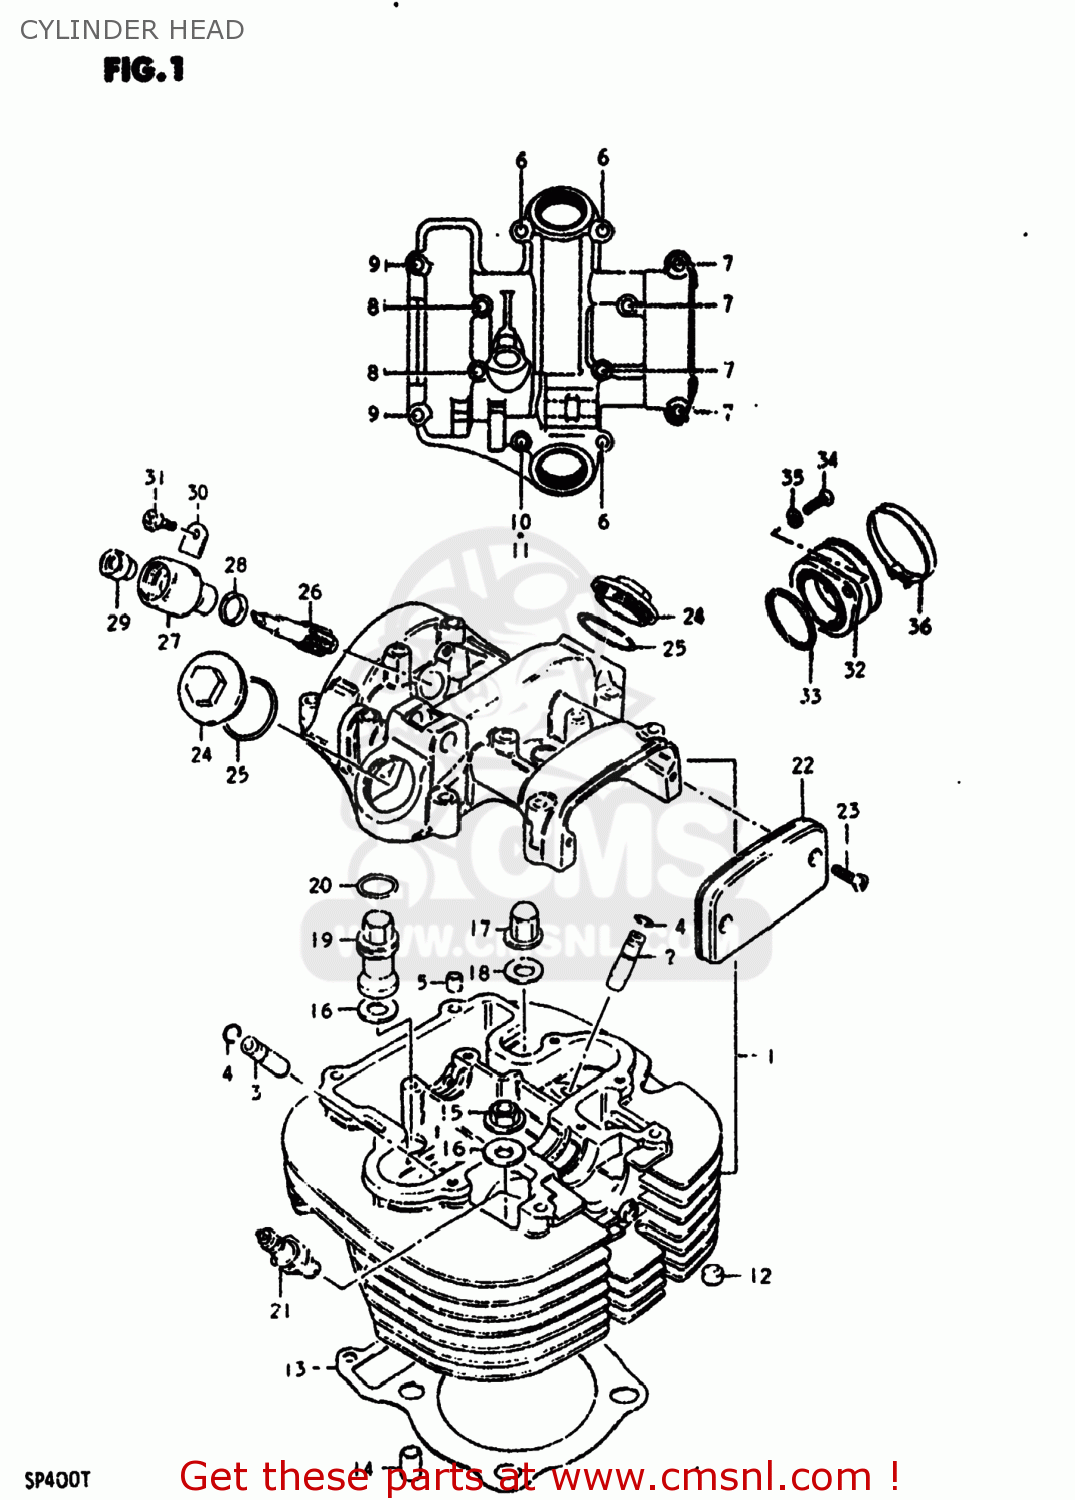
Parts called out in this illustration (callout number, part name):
1	HEAD ASSEMBLY,CYLINDER
2	GUIDE,INTAKE VALVE
3	GUIDE,EXHAUST VALVE
4	RING,SNAP
5	PIN(6.2X8X11)
6	BOLT 6X35
7	BOLT ,6X50
8	BOLT 6X65
9	BOLT(6X125)
10	BOLT
11	GASKET (NAS)
12	PAD,CYLINDER
13	GASKET,CYLINDER HEAD (NAS)
14	PIN
15	NUT
16	WASHER(10.5X22X2.3)
17	NUT
18	GASKET(10.5X22X2) (NAS)
19	NUT,CYLINDER HEAD SEAL
20	O RING(D:2.4,ID:17.8)
21	SPARK PLUG D8EA
22	CAP,CYLINDER HEAD COVER
23	SCREW
24	CAP,INSPECTION
25	O RING(D:3,ID:29.5)
26	GEAR,TACHOMETER DRIVEN
27	SLEEVE,TACHOMETER DRIVE
28	SEAL,TACHOMETER DRIVEN
29	SEAL,OIL(5X12X8)
30	PLATE,TACH DRIVE GEAR SLEEVE
31	SCREW(5X12)
32	PIPE,INTAKE
33	O-RING (D:2.4 ID:39.7)
34	SCREW
35	LOCK WASHER
36	CLAMP
